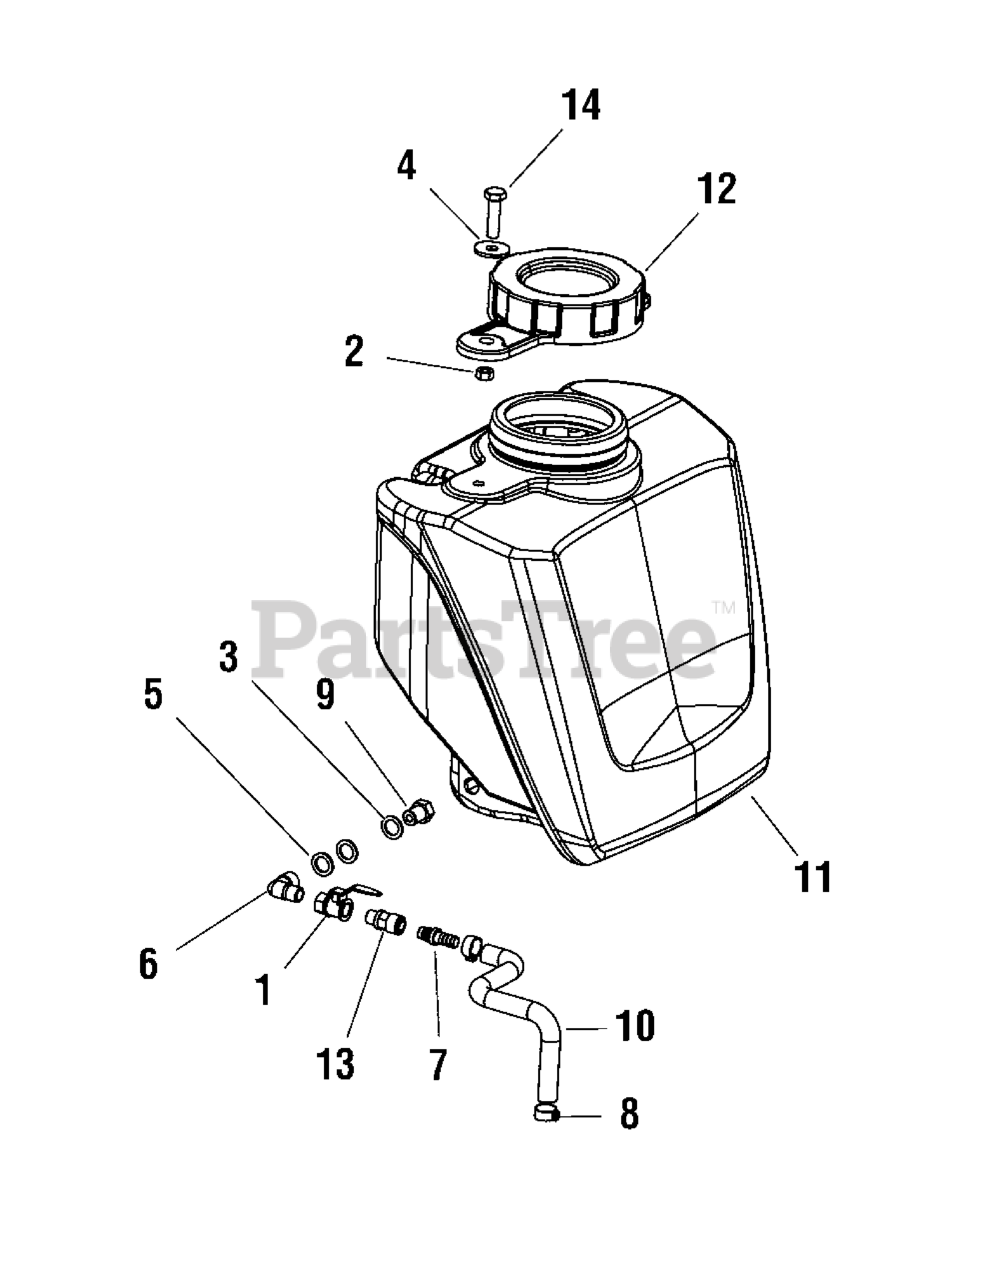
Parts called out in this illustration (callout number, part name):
1	VALVE, Brass Ball
2	NUT, Hex, M8
3	WASHER, Asbestos
4	WASHER, Flat, Large
5	WASHER, Flat
6	PIPE JOINT, L-Type
7	QUICK CONNECTOR, Male Joint
8	CLAMP, Spring
9	PIPE JOINT, T-Type
10	WATER HOSE
11	WATER TANK
12	COVER, Water Tank
13	QUICK CONNECTOR, Female Joint
14	BOLT, Hex, M10 x 35
